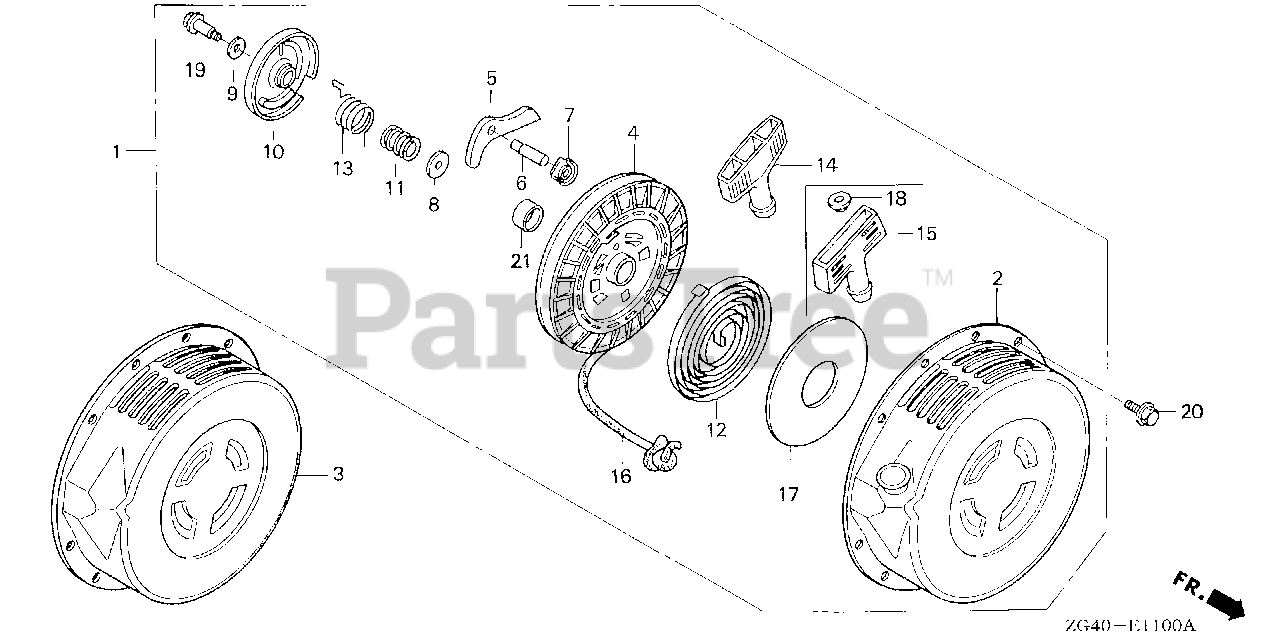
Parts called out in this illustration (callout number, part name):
1	STARTER ASSY., RECOIL *NH116M* (URBAN SILVER METALLIC)
2	CASE, STARTER
4	REEL, STARTER
5	RATCHET, STARTER
6	SHAFT, RATCHET
7	PLATE, GUIDE
8	PLATE A, FRICTION
9	PLATE B, FRICTION
10	COVER, STARTER REEL
11	SPRING, FRICTION
12	SPRING, RETURN
13	SPRING, TORSION
15	GRIP, STARTER
16	ROPE, STARTER
18	GRIP, REINFORCEMENT
19	BOLT (6MM)
20	BOLT, FLANGE (6X8)
21	COLLAR
